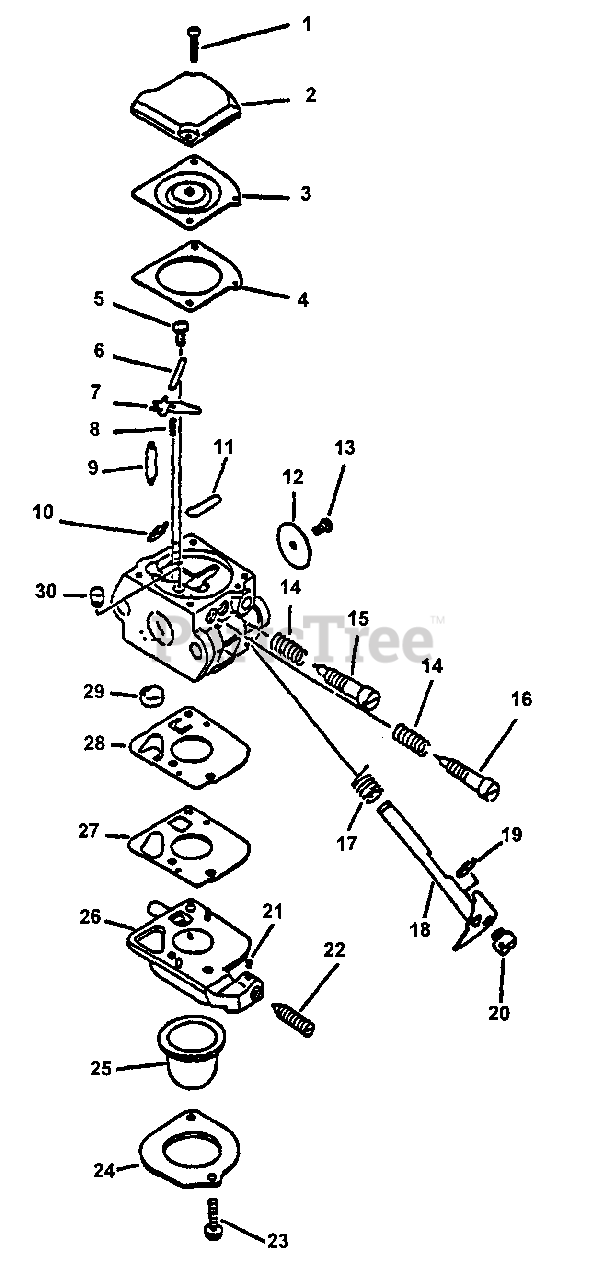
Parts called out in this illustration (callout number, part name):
2	COVER, METERING
3	DIAPHRAGM, METERING
4	GASKET, DIAPHRAGM
5	SCREW, METERING LEVER PIN
6	PIN, METERING LEVER
7	LEVER, METERING
8	INLET, LEVER
9	VALVE, INLET NEEDLE
10	RING, RETAINING
11	PLUG, WELCH
12	VALVE, THROTTLE
15	NEEDLE - LOW SPEED
16	NEEDLE - MIXTURE
17	SPRING, RETURN
18	SHAFT, THROTTLE
19	RING, RETAINING
21	PIECE, FRICTION
22	SCREW, IDLE ADJUST
23	SCREW, RETAINER
24	RETAINER, PURGE BULB
25	BULB, PURGE
26	BASE, PURGE
27	GASKET, PUMP
28	DIAPHRAGM, PUMP
29	STRAINER
30	NOZZLE, CHECK VALVE
